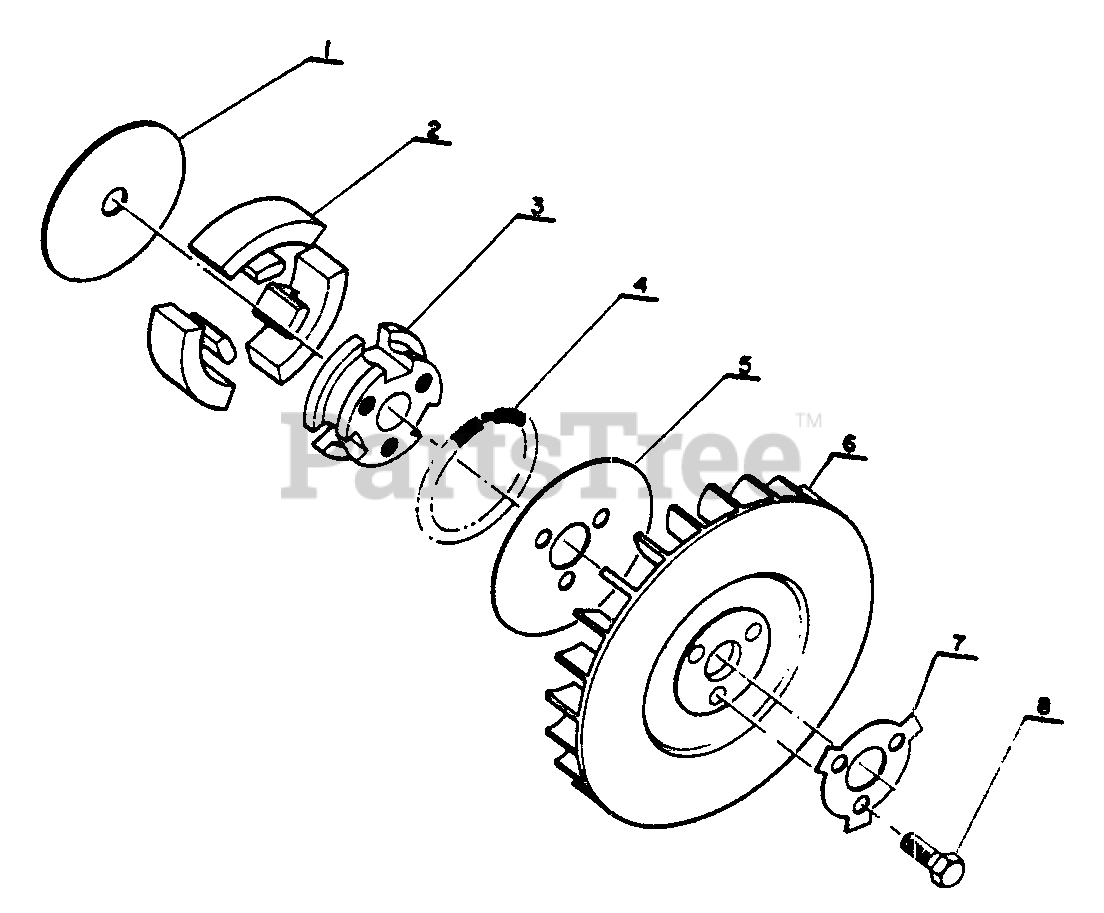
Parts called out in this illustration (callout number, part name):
1	SIDE PLATE, CLUTCH (A)
2	SHOE, CLUTCH
3	HUB, CLUTCH
4	SPRING, CLUTCH
5	SIDE PLATE, CLUTCH (B)
7	LOCKWASHER
8	BOLT - 5×14
